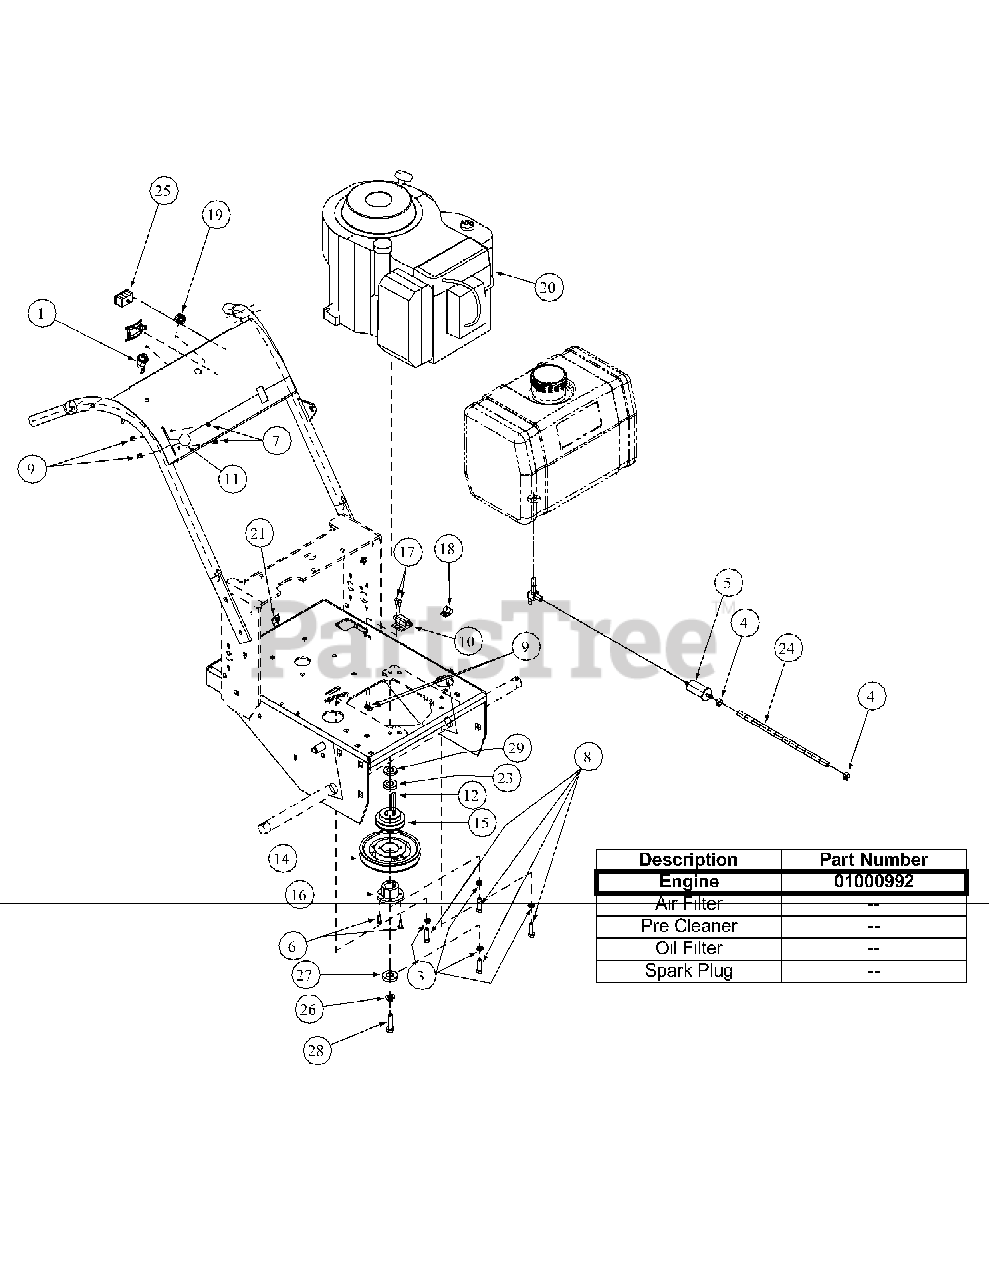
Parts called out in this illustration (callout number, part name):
1	Single Ignition ON/OFF Switch
2	Harness Hour Meter
3	Lock Washer, 5/16
4	Clamp
5	Kohler Fuel Filter
6	Harness Adapter,
7	Screw, Hex Washer, 10-32 x 1/2
8	Cap Screw, 1.25 x 30
9	Lock Nut, Nylon Insert, 10-32
10	Delta Switch
11	Control Throttle w/Detent, 39.2
12	Key Stick, 1/4 x 1/4 x 2-1/4
13	Harness Wire
14	Deck Pulley
15	Traction Pulley
16	Bushing
17	Machine Screw, 10-32 x 5/8
18	Support Clamp Tubing, 1/2"
19	Nut w/cap, 5/8-32 Ignition
20	13HP Kohler Engine
21	Support Clamp, 3/8 OD
22	Belt
23	Flat Washer
25	Hour Meter
26	Lock Washer, 7/16
27	Clutch Washer
28	Hex Cap Screw, 7/16-20 x 1.25 Lg
29	Spacer, Engine Pulley
